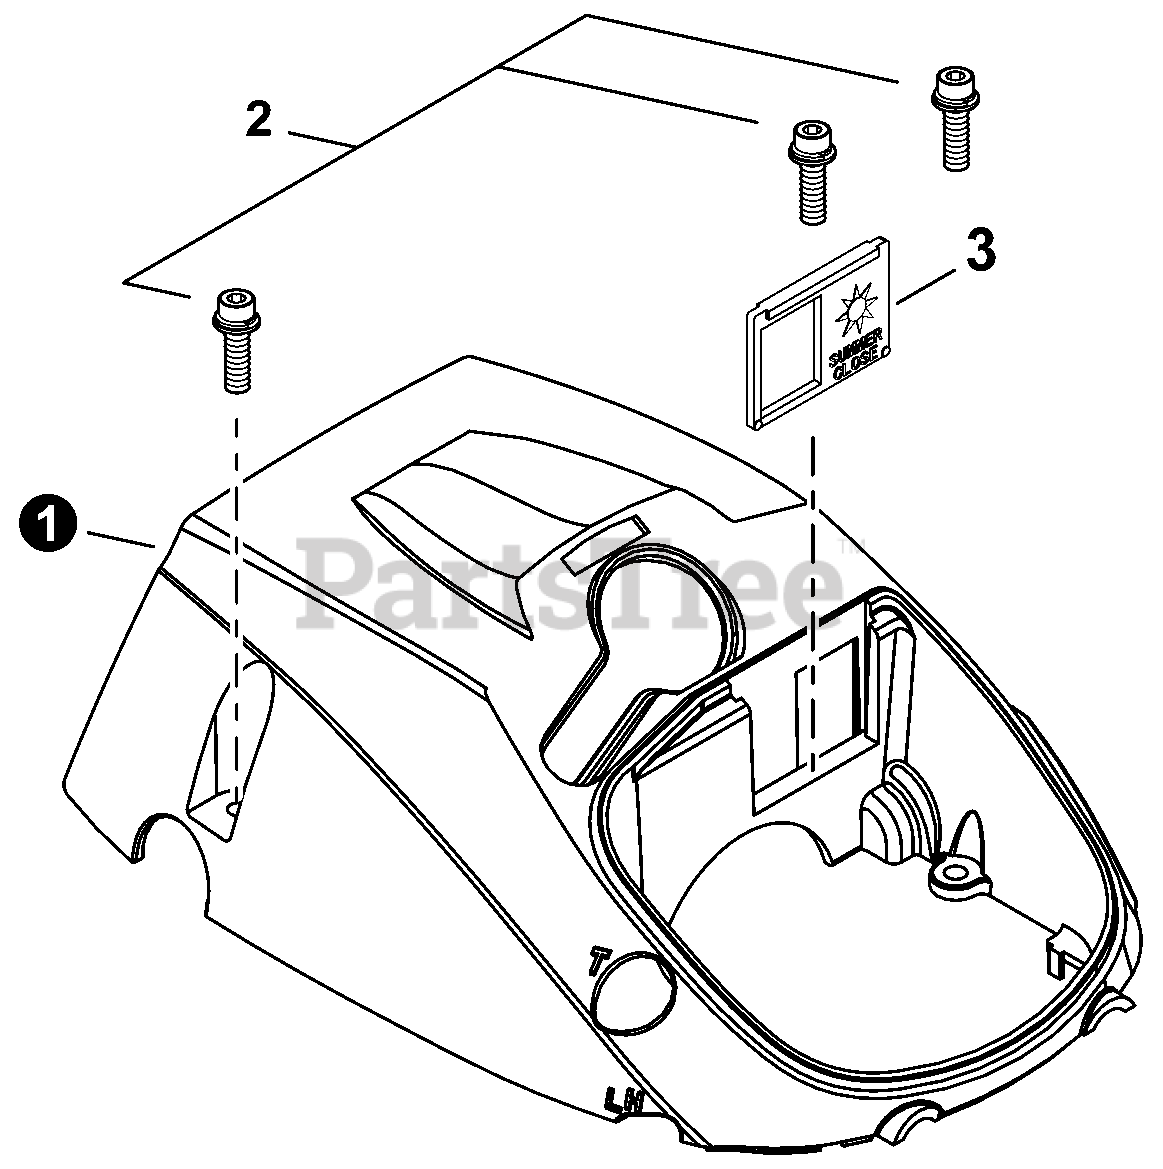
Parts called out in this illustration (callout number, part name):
1	COVER, ENGINE
2	BOLT M4×14
3	PLATE, SHUTTER
